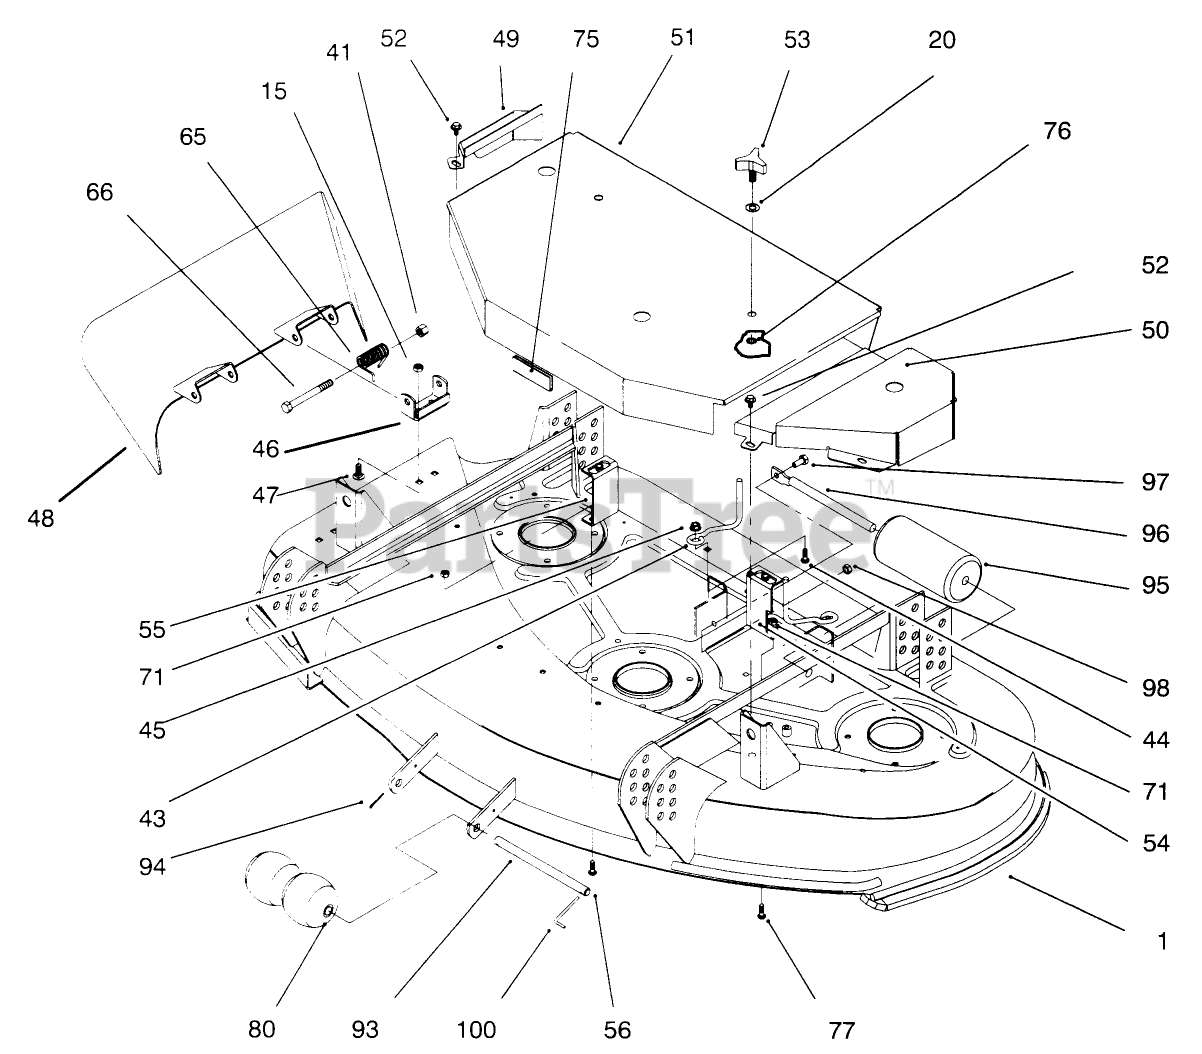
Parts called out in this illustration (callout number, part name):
1	44" Recycler Deck
15	NUT-LOCK, CONE
20	WASHER-FLAT
41	NUT-HEX
43	ROD-BELT
44	BOLT-CARR
45	NUT-HF
46	Bracket-Pivot
47	SCREW-CARR
48	Deflector-Grass
49	Cover-RH
50	Cover-LH
51	Cover-Deck
52	SCREW-HHFTF
54	Bracket-Cover
55	Bracket-Cover RH
56	BOLT-CARR
65	SPRING
66	SCREW-HH
71	NUT-LOCK, NI
75	TRIM-JIFFY
76	RING-RETAINING
77	SCREW-CARR
80	ROLLER
93	SHAFT-ROLLER
94	PIN-COTTER
95	ROLLER-DECK
96	ROD-ROLLER
97	SCREW-HH
98	NUT-LOCK, NI
100	PIN-SPECIAL
